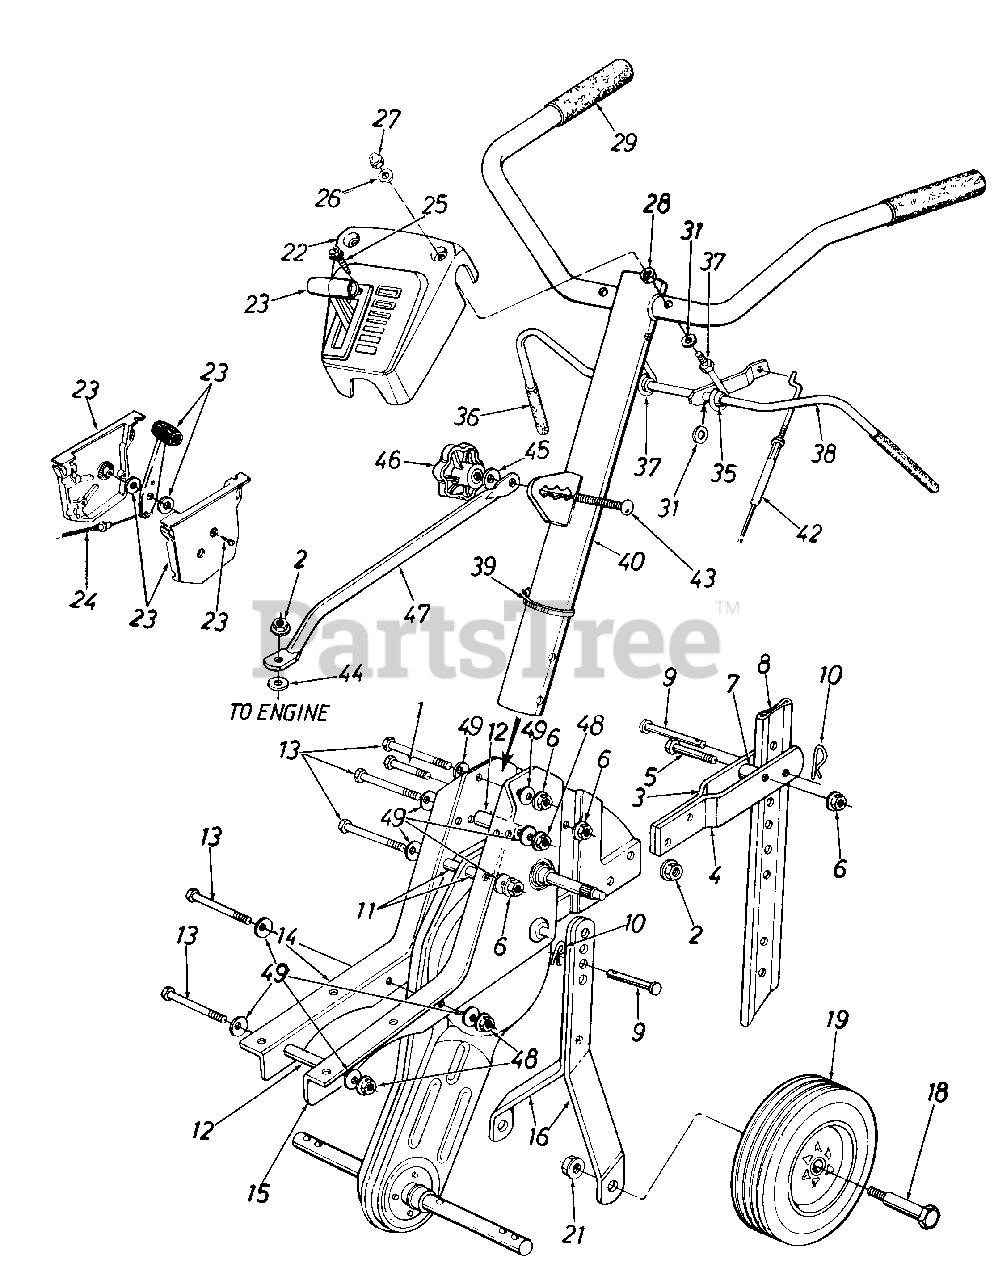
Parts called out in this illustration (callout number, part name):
1	Hex Bolt 5/16-18 x 1.25" Lg.
2	Hex Flange L-Nut 5/16-18 Thd. (Gr. 5)
5	Hex Bolt 5/16-18 x 1.5" Lg.
6	Hex Flange L-Nut 5/16-18 Thd. (Gr. 5)
7	Spacer .32" I.D. x .75" O.D.
9	Clevis Pin .375" I.D. x 1.75" Lg.
10	Internal Cotter Pin
11	Spacer .326" I.D. x .47" O.D.
12	Spacer .322" I.D. x .44" O.D.
13	Hex Bolt 5/16-18 x 2.75" Lg.
19	Wheel Ass'y.
21	Hex Flange L-Nut 3/8-16 Thd. (Gr. 5)
22	Handle Cover
23	Throttle Control Box Ass'y.
24	Throttle Control Wire 30.5" Lg.
25	Truss Mach. AB-Tap Scr. #10 x .5" Lg.
26	Fl-Wash. .266" I.D. x .625" O.D.
27	Hex L-Stop Nut 1/4-28 Thd.
28	Hex Nut 1/4-28 Thd.
29	Grip--Handle
31	Fl-Wash. .385" I.D. x .62" O.D.
35	Plastic Bushing .38" I.D.
36	Grip--Clutch
37	Clutch Handle Eye Bolt
43	Carr. Bolt 5/16-18 x 1" Lg.
44	Fl-Wash. .344" I.D. x 1.12" O.D.
45	Bell-Wash. .345" I.D. x .88" O.D.
46	Hand Knob
49	Bell-Wash. .345" I.D. x .88" O.D.
